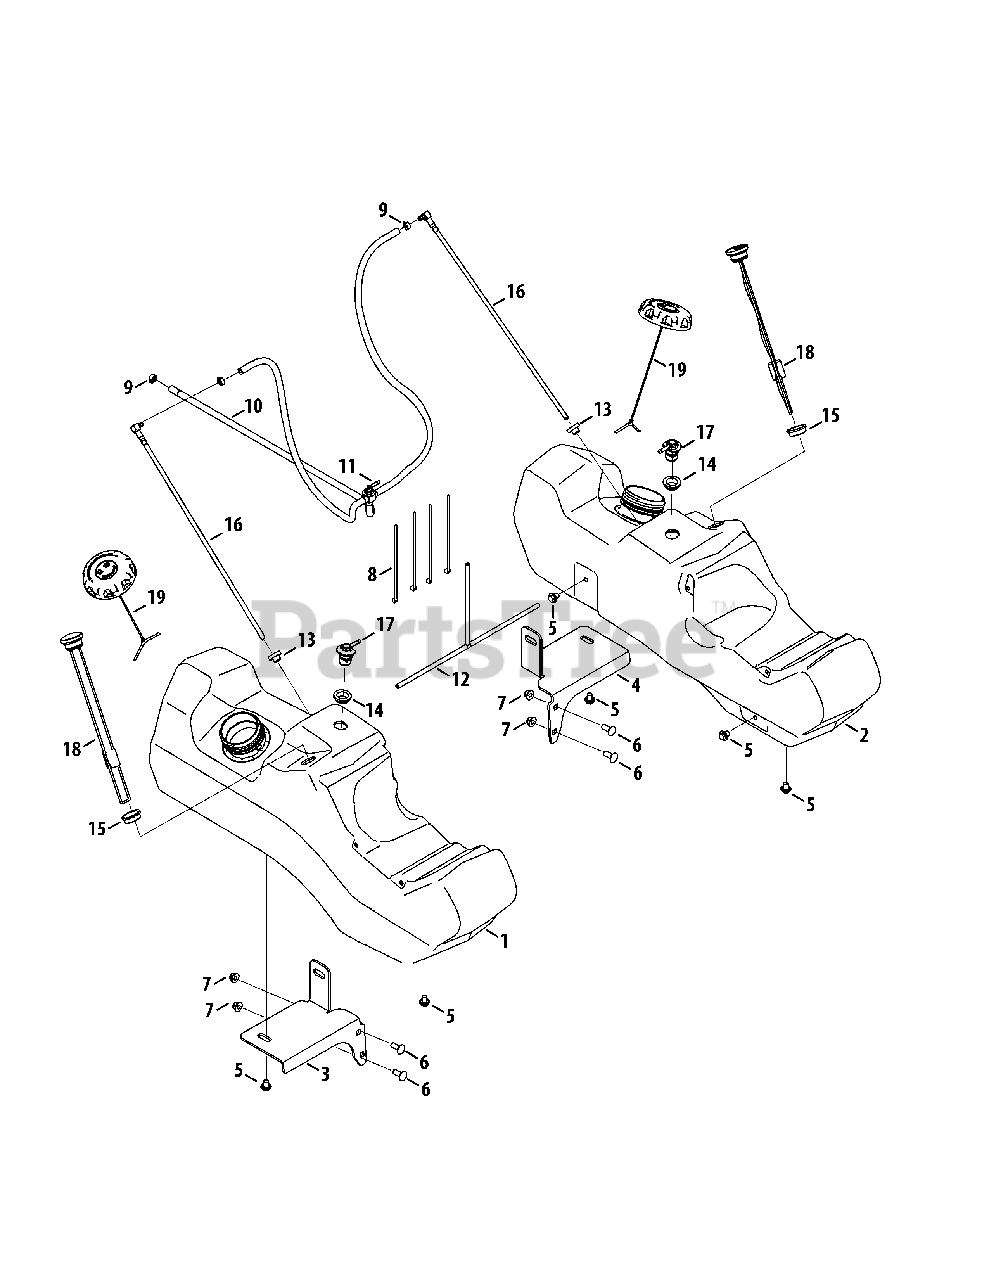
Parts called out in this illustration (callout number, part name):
1	Fuel Tank Assembly, RH
2	Fuel Tank Assembly, LH
3	Rear Fuel Bracket, RH
4	Rear Fuel Bracket, LH
5	Hex Cap Screw, 3/8-16 x .500
6	Carriage Bolt, 3/8-16 x .500
7	Nut, 3/8-16, Flangelock
8	Cable Tie
9	Hose Clamp, .500 Dia.
10	Fuel Hose., 1/4
11	Fuel Switch
12	Fuel Hose Assembly
12	Tee Fitting, Fuel
13	Grommet, Fuel Tank
14	Rubber Grommet
15	Grommet, 1.58 OD x 1.21 ID x .5
16	Fuel Pickup Valve
17	Fuel Rollover Valve
18	Fuel Gauge
